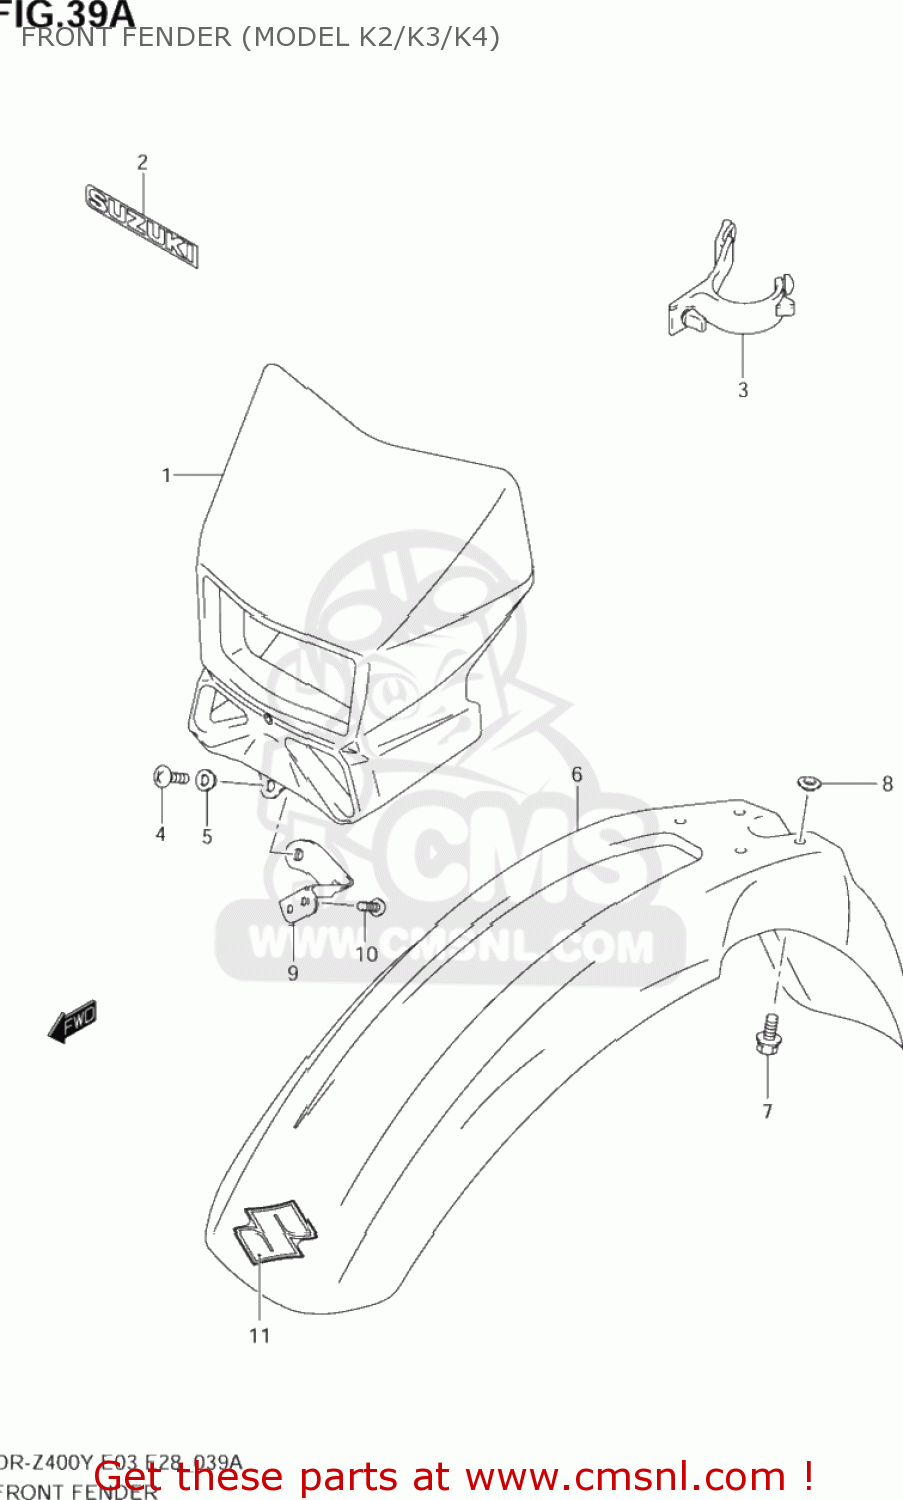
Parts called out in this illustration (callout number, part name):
1	COVER,HEADLAMP(WHITE)
2	EMBLEM,SUZUKI
3	BAND,HEADLAMP COVER
4	SCREW(5X12)
5	WASHER
6	FENDER,FR
7	BOLT(6X16)
8	WASHER
9	BRACKET,HEADLAMP COVER
10	SCREW(6X16)
11	EMBLEM,FR FENDER
